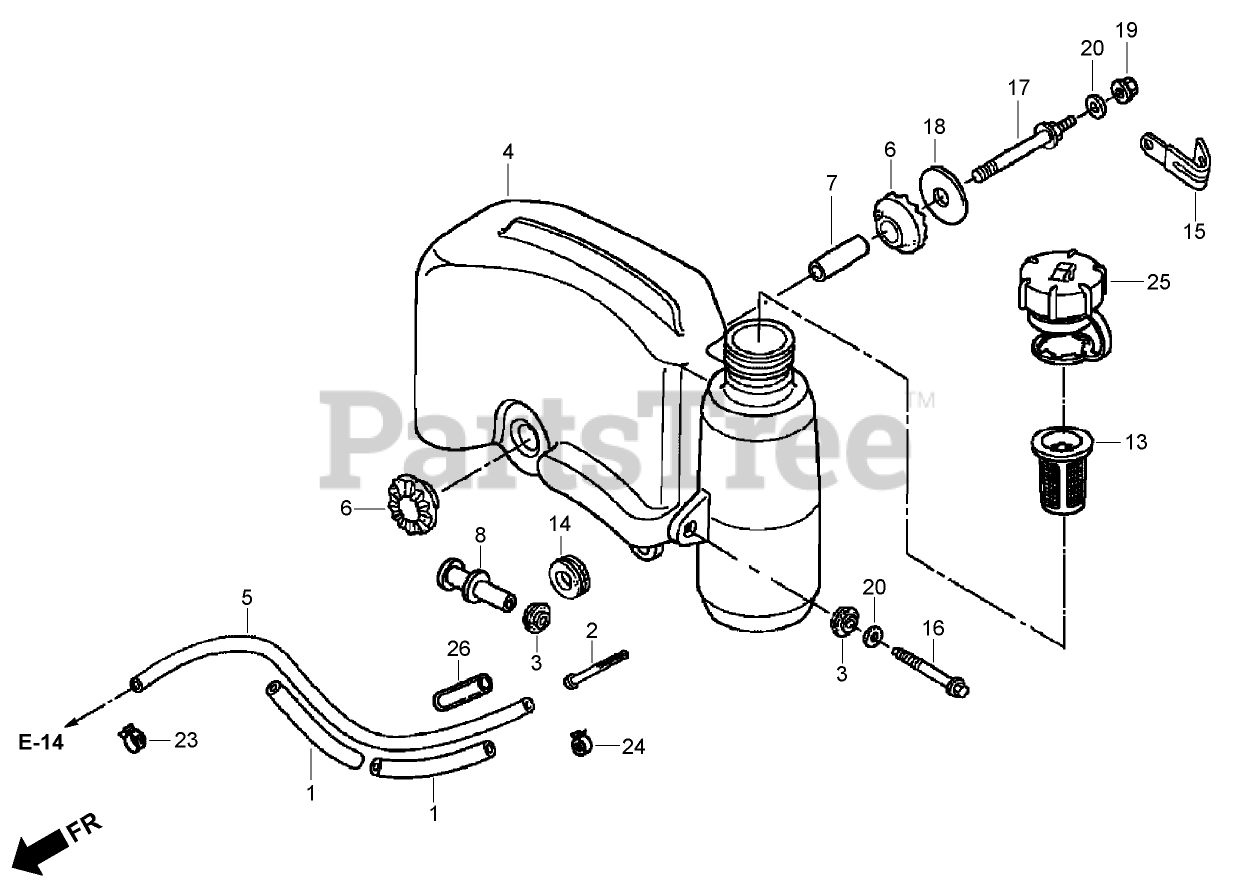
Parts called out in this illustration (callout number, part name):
1	SUPPORTER-RUBBER (107 mm)
2	FILTER-FUEL
3	RUBBER-SETTING, TANK
4	TANK-FUEL
5	TUBE-FUEL (F K M)
6	RUBBER B-MOUNTING, TANK
7	COLLAR-SET, TANK
8	COLLAR-TANK
13	GAUGE-LEVEL, FUEL
14	CUSHION-FENDER, R R
15	CLIP-TUBE
16	BOLT-FLANGE (6X47) (C T200)
17	BOLT-STAY, TANK
18	WASHER-MOUNTING, TANK
19	NUT-FLANGE (6 mm)
20	WASHER-PLAIN (6 mm)
23	CLAMP-TUBE (D8) (engine serial numbers starting at 3698327)
24	CLAMP-TUBE (D105) (Engine Serial No. From 1011284)
25	FUEL TANK CAP ASM
26	HOSE-BULK, VINYL (9X11X3000) (9X11X30)
